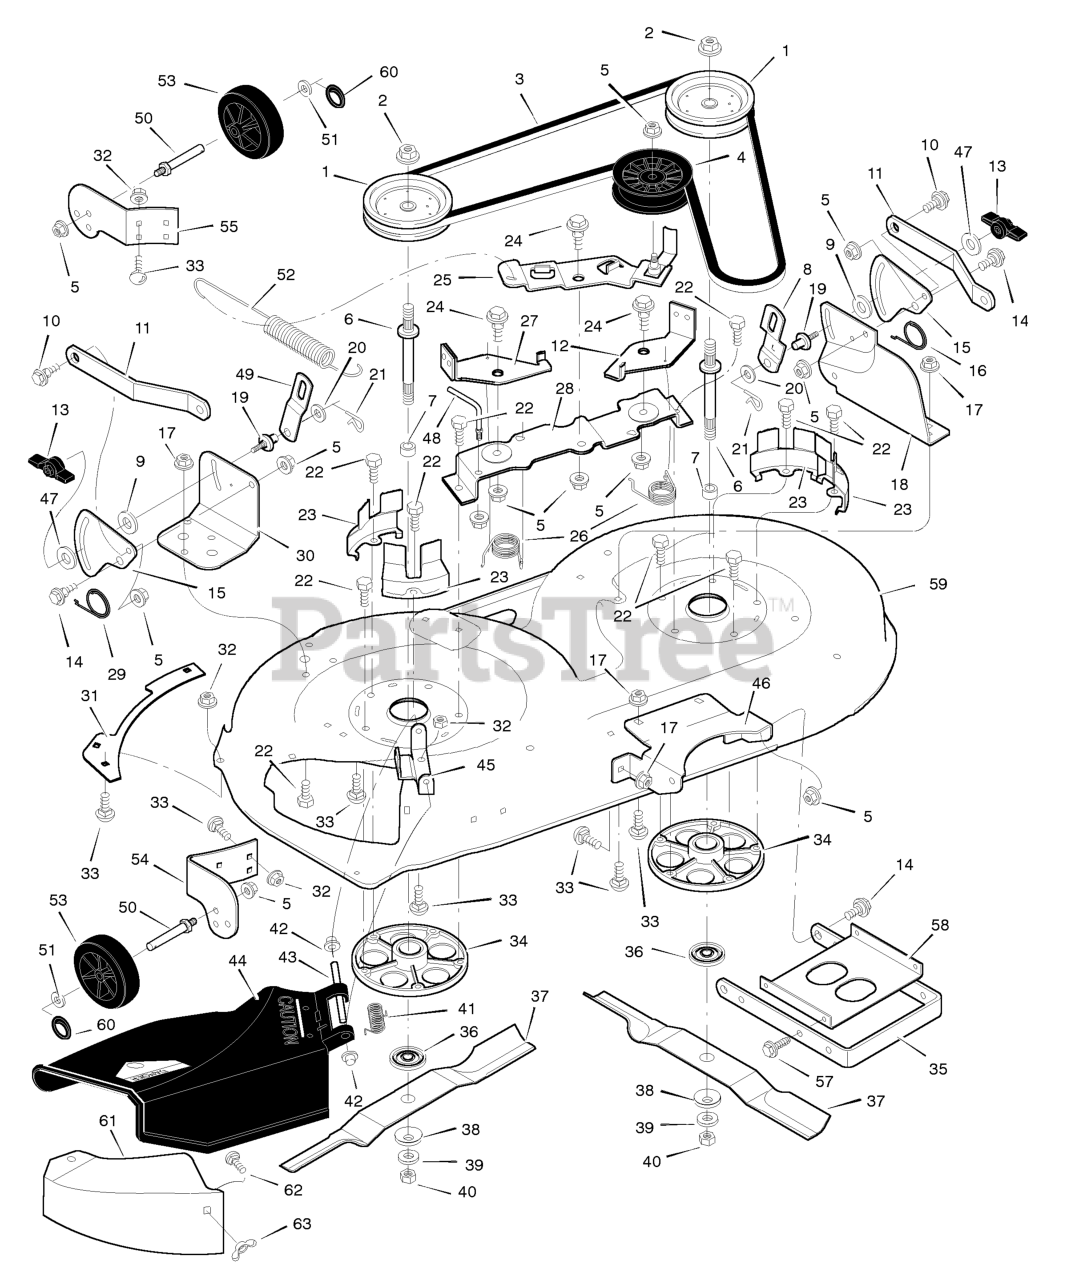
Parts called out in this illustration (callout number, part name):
1	Pulley, Jackshaft
2	Nut, Hex
3	Belt, Mower Drive
4	Pulley, Idler
5	Nut, Flange
6	Jackshaft
8	Link, Left Lift
9	Pad, Friction
10	Bolt, Shoulder
11	Bracket, Suspension
12	Pad Assembly, Left Brake
13	Knob
14	Bolt, Shoulder
15	Plate, Suspension
17	Nut, Flange
18	Bracket, Suspension
19	Pin, Hanger
21	Pin, Hair
22	Bolt
23	Cover, Pulley
24	Bolt, Shoulder
25	Arm, Idler
27	Pad Assembly, Right Brake
28	Bracket, Brake
30	Bracket, Suspension
32	Nut, Flange
33	Bolt, Carriage
34	Mandrell Housing
35	Bracket, Suspension
36	Adapter, Blade
42	Cap, Push On
43	ROD, Deflector
44	Deflector Assembly
45	Bracket, Deflector Hinge
46	Bracket, Front Hanger
48	Guide, Belt
49	Link, Right Lift
50	BOLT, Gauge Wheel
52	Spring, Extension
53	Wheel, Gage
54	Bracket, Right Wheel
55	Bracket, Left Wheel
58	Stiffener
59	Housing, Blade, Complete (NO LONGER AVAILABLE)
59	Housing, Blade (Housing Only)
60	Ring, Locking
61	Cover, Mulcher
62	Bolt, Carriage
63	Wingnut
